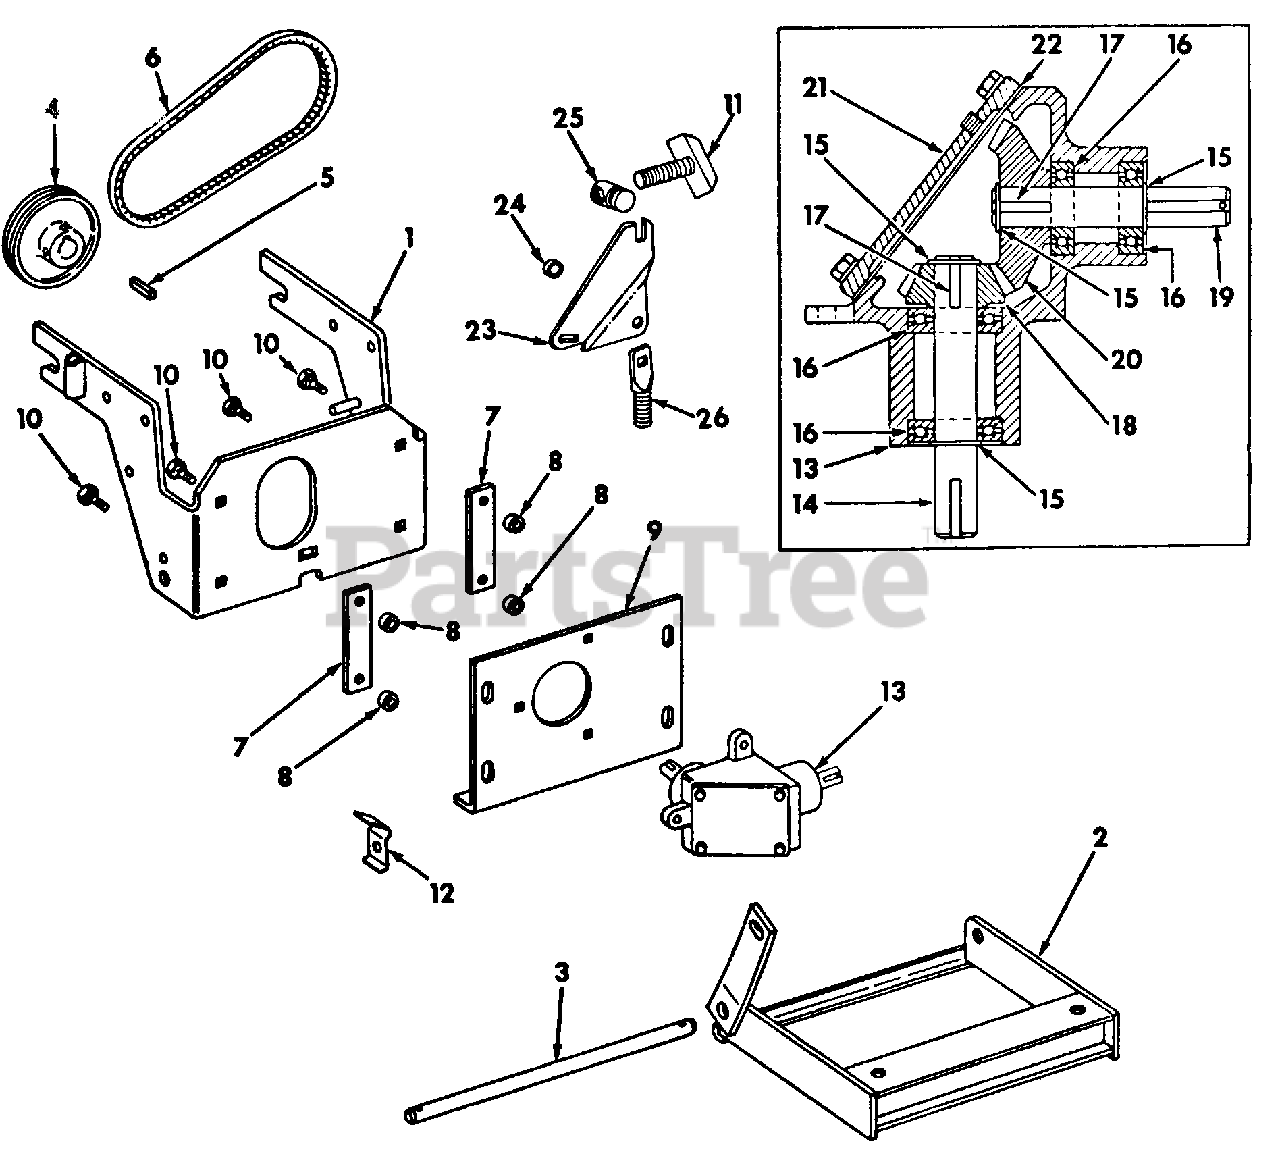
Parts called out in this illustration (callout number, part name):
1	Plate Assy, Front Mounting
2	Bracket Assy, Lift
3	Shaft, Pivot
4	Pulley, Gear Box -Replaces 475 613 R91
5	Key, 3/16 X 1-1/4 Sq Parallel
7	Spacer, Plate
9	Plate, Gear Box Mounting
10	Bolt, Shoulder
11	Bolt Assy, Belt Adj
12	Plate, Lock
14	Shaft, Input
15	Ring, Retaining Snap
16	Bearing, Inner
17	Key, 3/16 X 11/16 Sq Parallel
18	Gear, Bevel Pinion
19	Shaft, Output
20	Gear, Bevel
21	Cover, Gear Box
22	Gasket, Gear Box Cover
23	Plate, Pivot
25	Nut, Swivel
